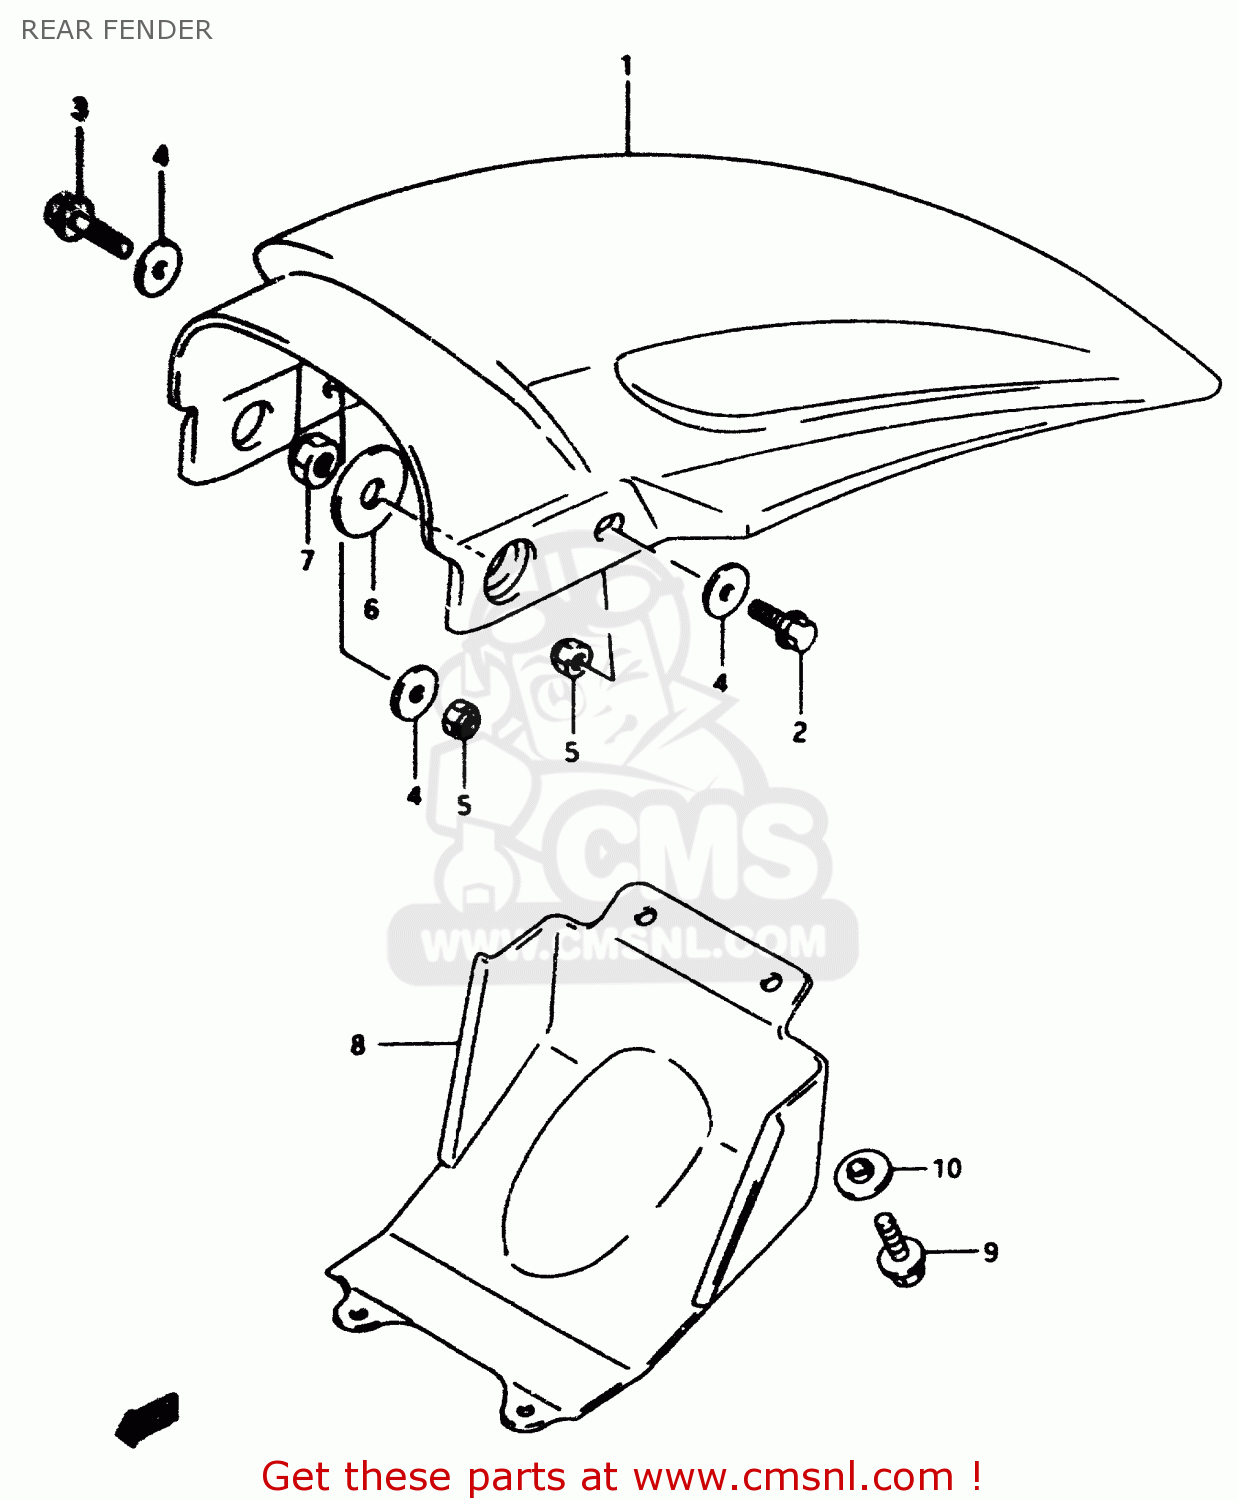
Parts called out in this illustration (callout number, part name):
1	FENDER,RR
2	BOLT
3	BOLT,G/S SWITC
4	WASHER(6.5X20X1.6)
5	NUT
6	WASHER (10.5X30X2.3)
7	NUT
8	MUDGUARD,RR FENDER FR
9	BOLT
10	WASHER
